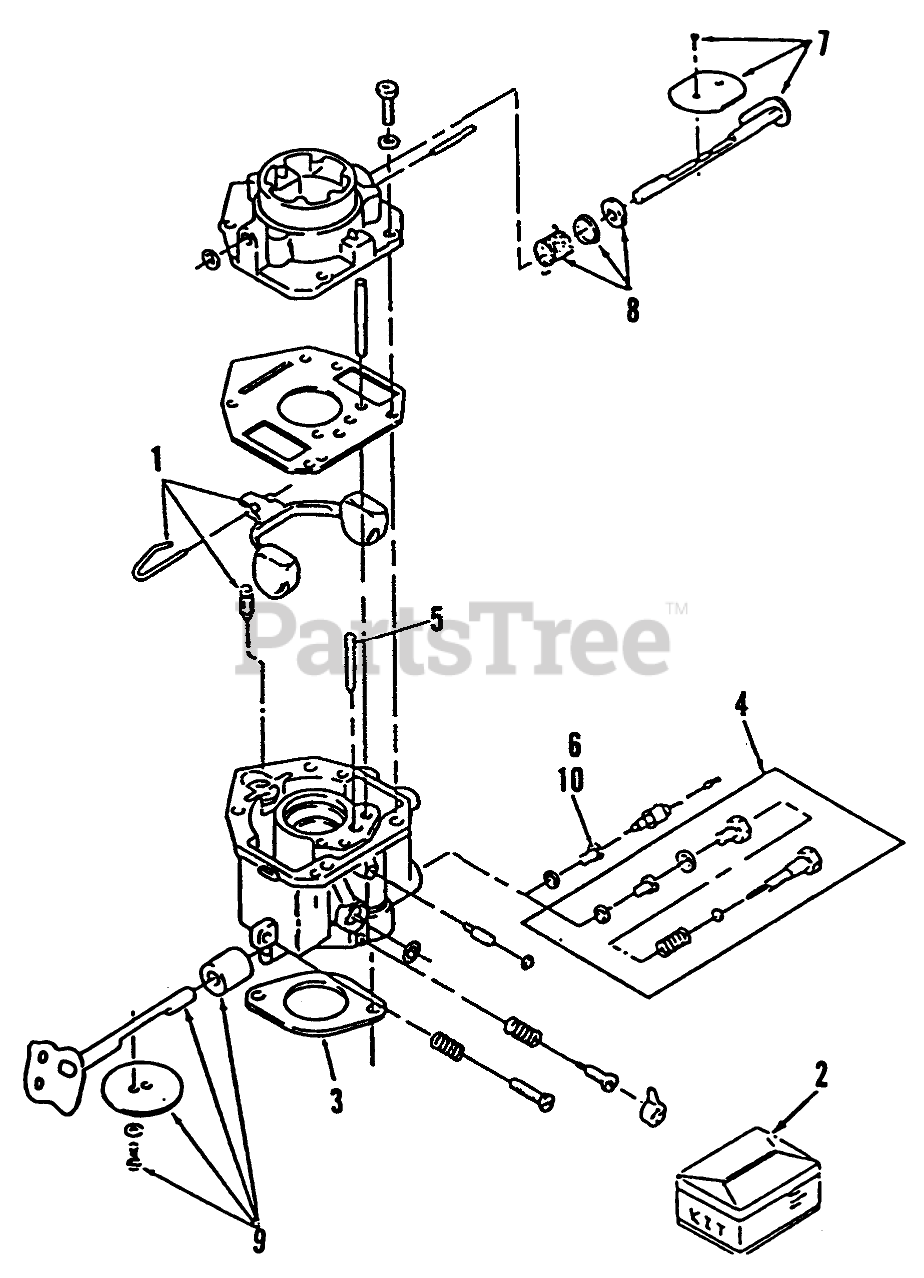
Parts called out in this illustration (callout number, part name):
1	Flat Kit (Includes Float Pin)
2	Carburetor Repair Kit
3	Gasket
4	FIXED-JET PKG
5	Idle Jet
6	POWER JET
7	Choke Shaft Kit
8	CHOKE-LEVER KIT
9	SHAFT-THROTTLE KIT
10	FIXED-JET PKG
